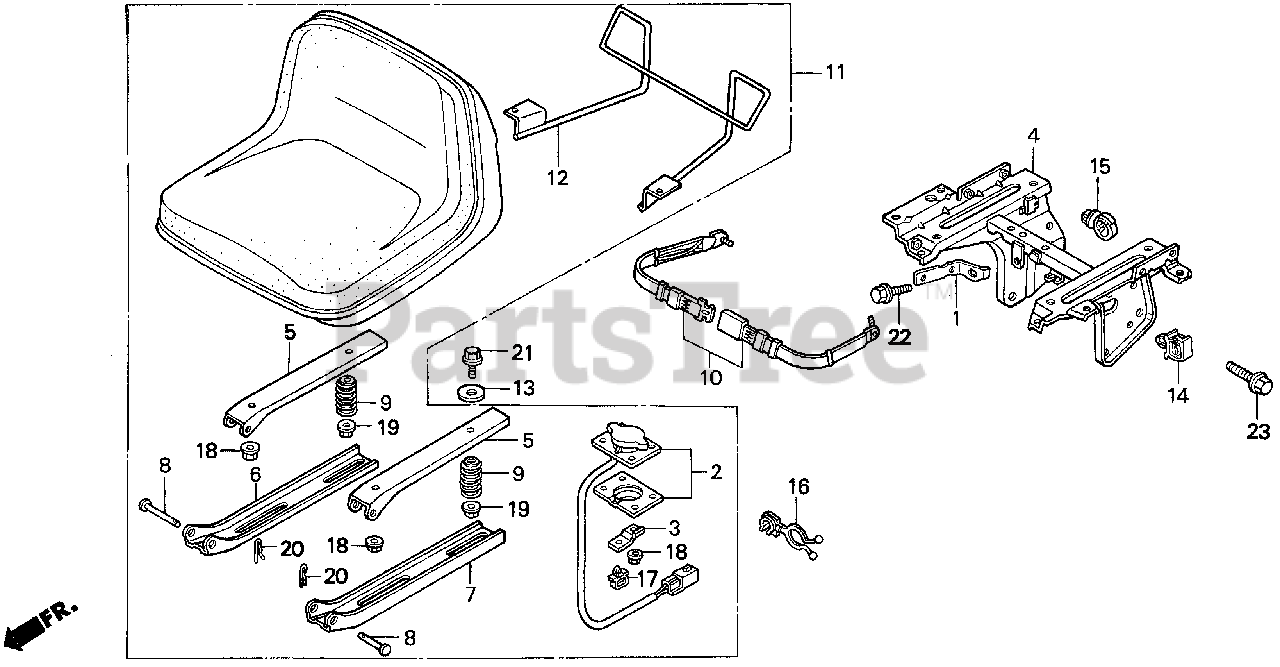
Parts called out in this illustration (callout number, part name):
1	BRACKET, HARNESS CLIP (B)
2	SWITCH ASSY., SEAT
3	BASE, CLIP
4	FRAME, SEAT SUPPORT
5	BASE, SEAT (UPPER)
6	BASE, R. SEAT (LOWER)
7	BASE, L. SEAT (LOWER)
8	PIN, SEAT BASE (8MM)
9	SPRING, SEAT
10	SEAT BELT ASSY.
11	SEAT ASSY.
12	HOLDER, TOOL BOX
13	WASHER, ROTOR SETTING
14	CLIP, HARNESS (15MM) (BLUE)
15	CLIP, WIRE HARNESS
17	CLIP, WIRE HARNESS (BLACK)
18	NUT, FLANGE (6MM)
19	NUT-WASHER (6MM)
20	PIN, LOCK (8MM)
21	BOLT, FLANGE (8X16)
22	BOLT, FLANGE (8X20)
23	BOLT, FLANGE (10X25)
